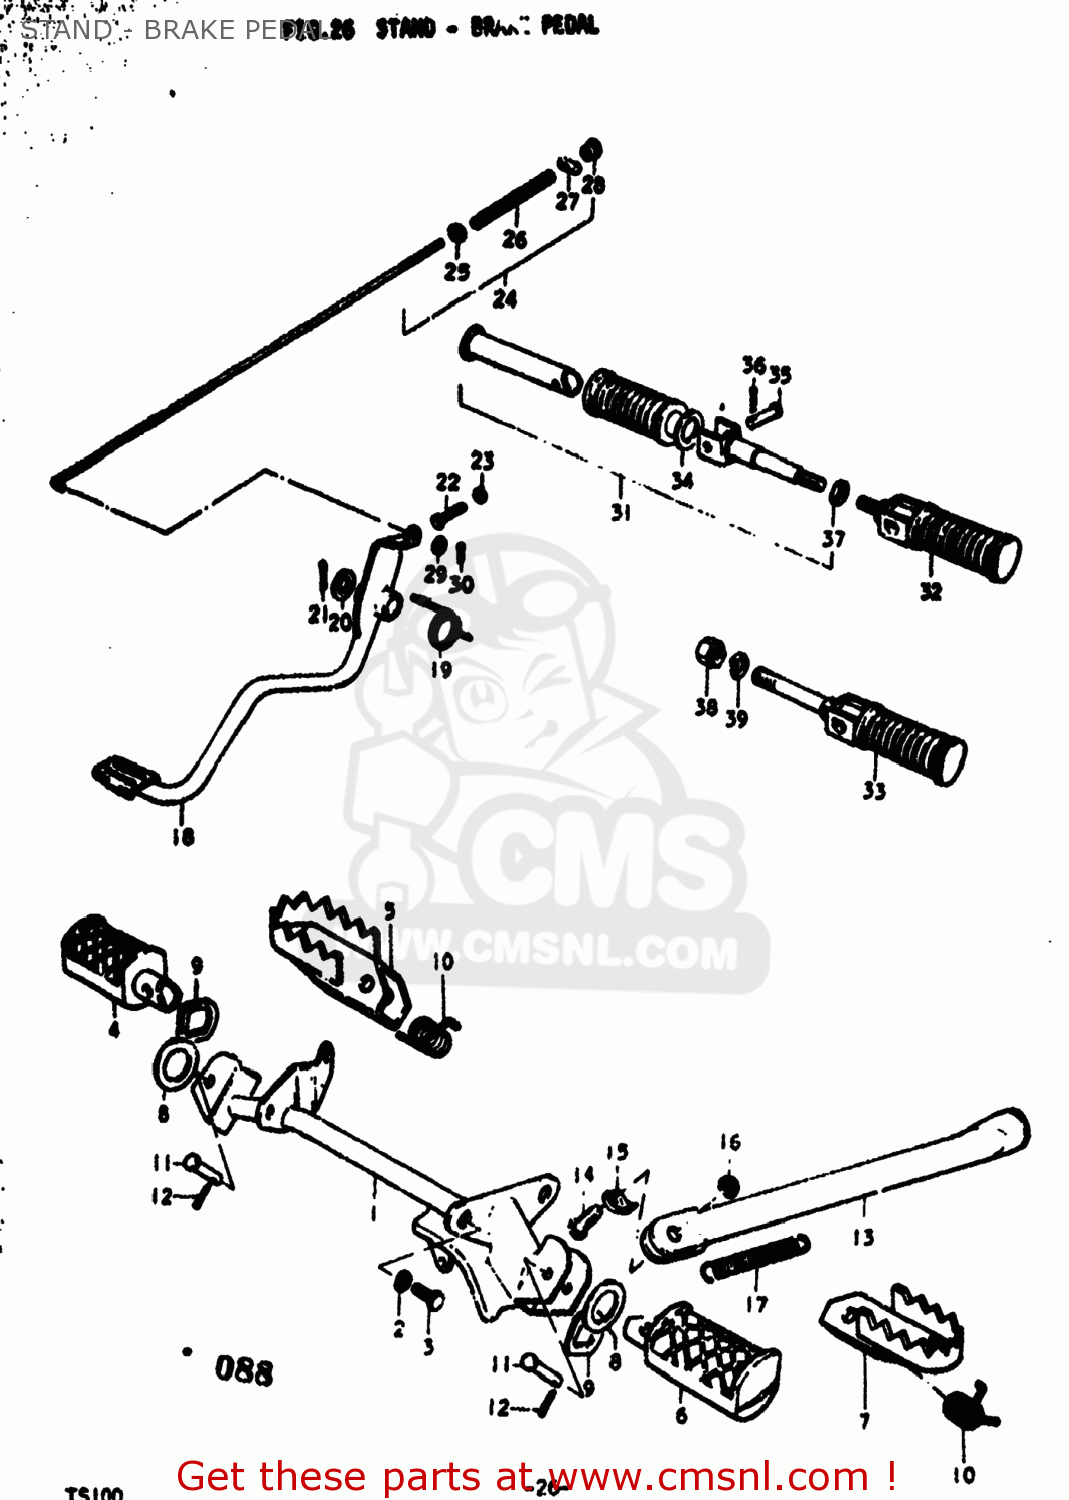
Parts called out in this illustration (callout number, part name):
1	BAR,FRONT FOOTREST
2	LOCK WASHER
3	BOLT
4	RUBBER,FOOTREST,RIGHT
5	RUBBER,FOOTREST,RIGHT
6	RUBBER,FOOTREST,LEFT
7	RUBBER,FOOTREST,LEFT
8	WASHER
9	WASHER
10	SPRING
11	PIN
12	PIN 20X20
13	STAND,SIDE
14	BOLT
15	WASHER
16	NUT
17	SPRING
18	PEDAL,BRAKE
19	SPRING
20	WASHER(15.5X26X2.3)
21	COTTER PIN
22	BOLT
23	NUT
24	ROD ASSEMBLY,REAR BRAKE
25	WASHER
26	SPRING
27	PIN(11X18)
28	NUT
29	WASHER
30	PIN 20X20
31	FOOTREST ASSEMBLY,REAR
32	FOOTREST ASSEMBLY,REAR
33	FOOTREST ASSY,PILLION
34	WASHER (19.5X32X2)
35	PIN
36	PIN 20X20
37	NUT
38	NUT
39	WASHER,LOCK 12
